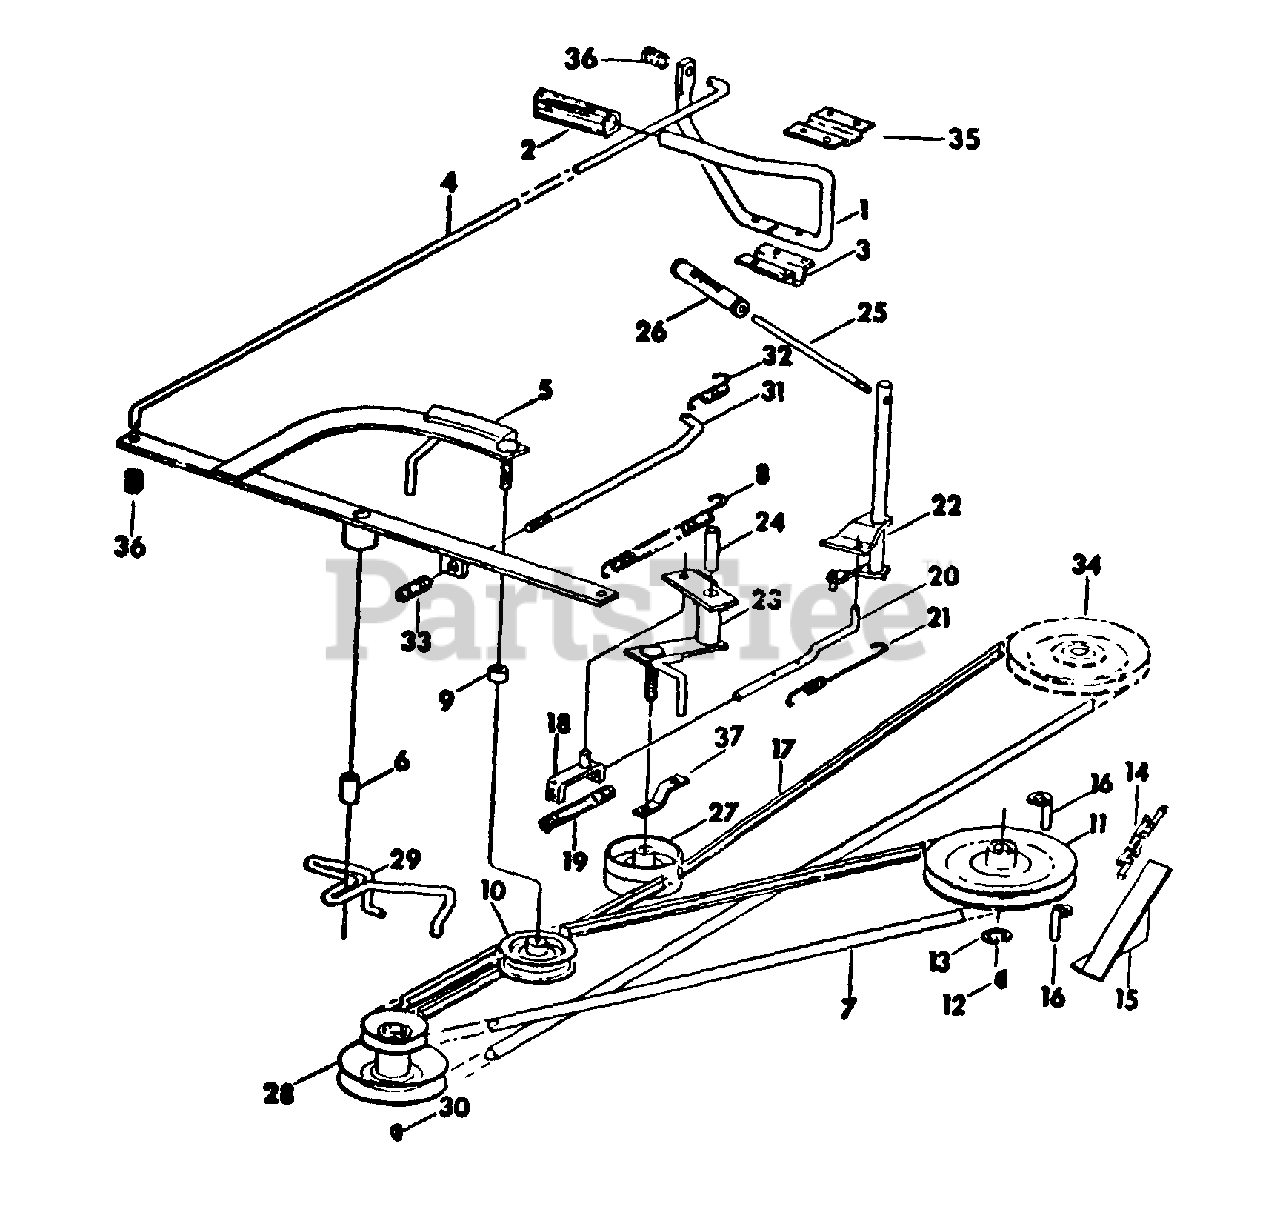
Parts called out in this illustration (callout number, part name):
1	PEDAL, CLUTCH AND BRAKE
3	CLAMP, PEDAL PIVOT
4	ROD, CLUTCH CONTROL
5	ARM ASSY, SHIFTER PIVOT
6	BUSHING, SHIFTER ARM
7	BELT, FORWARD DRIVE
8	SPRING, PEDAL RETURN
9	SPACER, 3/8 X .938 EXTRA STRONG PIPE
10	IDLER, BALL BRG
11	PULLEY, TRANSMISSION DRIVE
12	KEY, 3/16 X 3/4 WOODRUFF 9
13	RING, RETAINING
14	CHAIN, FINAL REDUCTION
15	SHIELD ASSY, DRIVE CHAIN
16	GUIDE, BELT
17	BELT, MOWER DRIVE
18	STRAP ASSY, IPTO
19	SPRING, IPTD
20	ROD, MOWER SHIFTER
21	SPRING, IPTO RETURN
22	LEVER ASSY, MOWER SKATER
23	LEVER ASSY, SHIFTER ARM
24	BUSHING, IPTO
25	ROD, SHIFTER HANDLE
26	GRIP, SHIFTER HANDLE
27	PULLEY, MOWER SHIFTER IDLER
28	PULLEY, ENGINE AND MOWER DRIVE
29	GUIDE, BELT PTO AND FORWARD DRIVE
30	KEY, 5/32 X 5/8 WOODRUFF 6
32	SPRING, BRAKE RETURN
33	SPRING, COMPRESSION
34	PULLEY, CENTER
35	SPRING, CLUTCH PEDAL
36	SPRING, ANTI RATTLE
37	RETAINER, MOWER BELT
